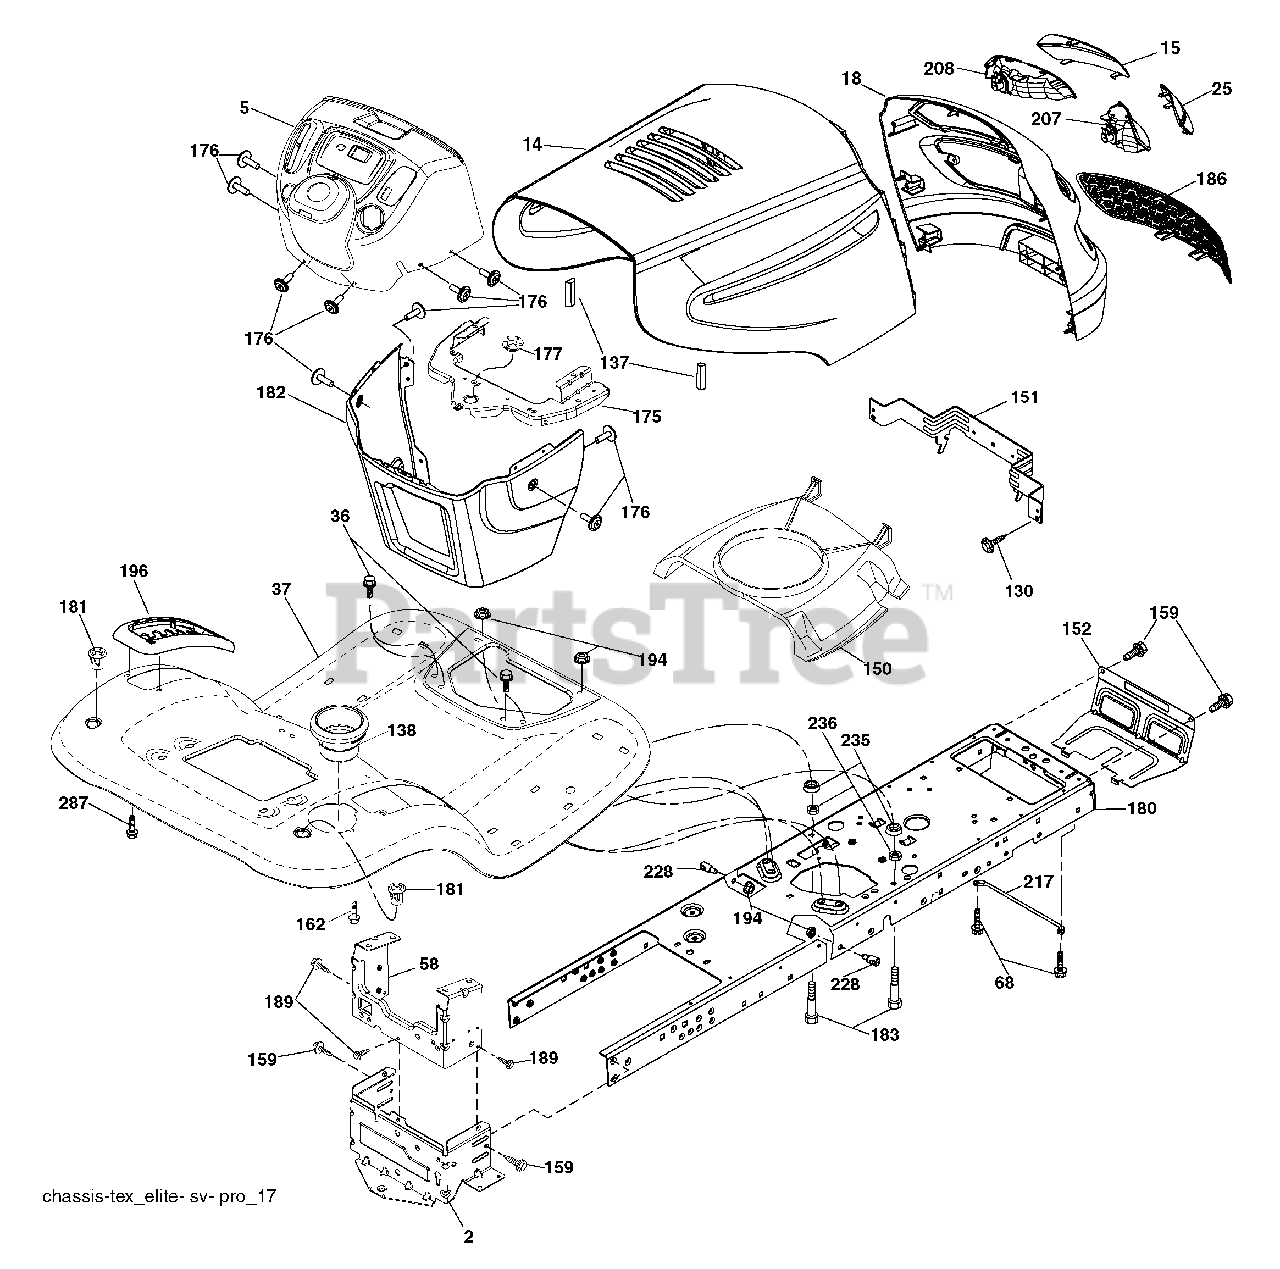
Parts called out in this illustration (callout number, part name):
2	Drawbar Lower
5	Dash
14	Hood
15	Lens Grille LH
18	Grille
25	Lens Grille RH
36	Screw 5/16-18 x 3/4
37	Fender
58	Drawbar Upper
68	Screw Thdrol 5/16-18 x 1/2
130	Screw #10 x 0.750 ROS Thread
137	Bumper Hood
138	Cupholder
150	Duct Heat Hood
151	Bracket Pivot
152	Shield Browning/Debris
159	Screw Hexwsh Thdrol 3/8-16 x 3/4
162	Screw Hex Wsh Hi-Lo 1/4 x 1/2
175	Crossmember
176	Screw 10-24 x 5/8 Wshd Qdrx
177	Bushing Steering
181	Bushing Mtg. Fender Crgo.
182	Dash Lower
183	Bolt Fin Hex 5/16-18 x 1-1/4
189	Screw 5/16-18 x3/4
194	Nut Lock Hex Flange 5/16-18
196	Console Asm. Deck Lift
207	Bezel Grille RH
208	Bezel Grille LH
217	Rod Pivot Chassis
228	Stud Fastener
235	Spacer Fender
236	Nut Center Lock 5/16-18
287	Screw Hex Washead 1/4-20 x 3/8
